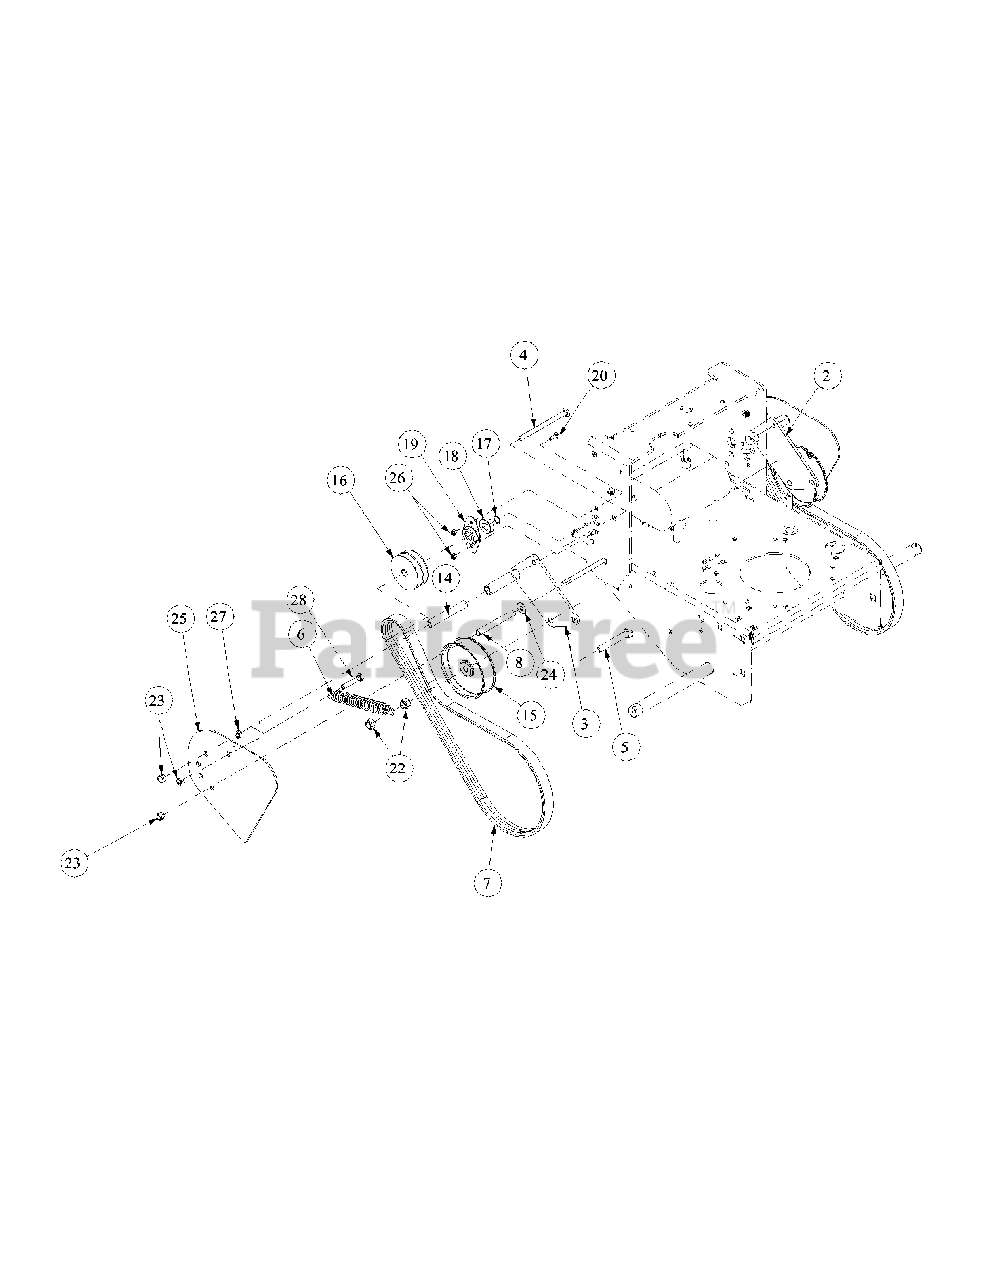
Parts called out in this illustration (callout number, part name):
2	Left Idler Bracket
3	Right Idler Bracket
4	Carriage Bolt, 3/8-16 x 5.50
5	Hex Cap Screw, 1/2-13, 3.50
6	Extension Spring,1.0 x 5.0
8	Spacer Tube
14	Idler Sleeve
15	Flat Idler Drive
16	Jackshaft Pulley
17	External Retain Ring
19	Bearing Housing
20	Carriage Bolt, 1/4-20 x .750
22	Lock Nut, Nylon Insert, 1/2-13
23	Lock Nut, Nylon Insert, 3/8-16
24	Flat Washer, 3/8 Zinc
25	Belt Guard
26	Lock Nut, Nylon Insert, 1/4-20
27	Hex Nut, 3/8-16
28	Hex Cap Screw, 3/8-16, 2.00
